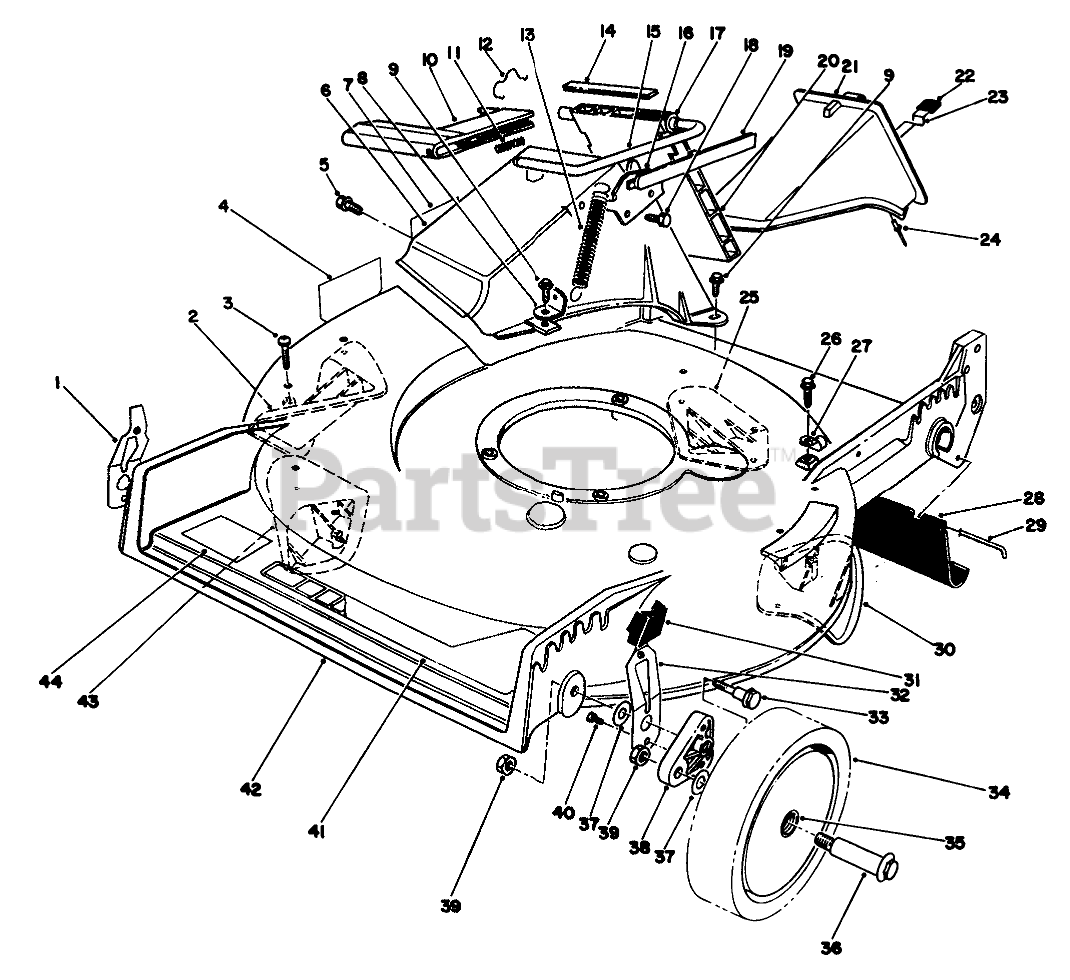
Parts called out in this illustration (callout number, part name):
1	RH SPRING ARM ASSEMBLY
2	KICKER
3	#8 X .625" PHILPS PAN H
4	DECAL-DANGER
5	SCREW AND WASHER ASM
6	DISCHARGE TUNNEL
7	Decal-Danger
8	Bracket-Spring
9	SCREW-HWH
10	Handle-Door
11	Spring
12	RETAINER-DOOR
13	SPRING-DOOR
14	Cover-Door
15	Rod-Door
16	Plate-Latch
17	BUSHING-NYLON
18	SCREW-PLASTITE
19	Cover-Handle
20	Door-Discharge
21	Plug-Discharge (Incl. Ref. #22-24)
22	GRIP-LATCH
23	LATCH-PLUG, DISCHARGE
24	RIVET-HEAD, FLAT
25	PLATE-KICKER
26	SCREW-HWHTF
27	CLAMP-R
28	HANDLE LATCH
29	ROD-SHIELD
30	KICKER
31	KNOB-ARM
32	LH SPRING ARM ASSEMBLY
33	SCREW-SHOULDER
34	Wheel & Tire Assembly (Incl. Ref. #35)
35	BUSHING
36	WHEEL BOLT
37	WASHER
38	ARM-PIVOT, FRONT
39	Nut
40	SCREW-HWH
41	DECAL - DECK
42	Housing Assembly (Incl. Ref. #2-4, 25, 30 &43)
43	KICKER
44	DECAL
